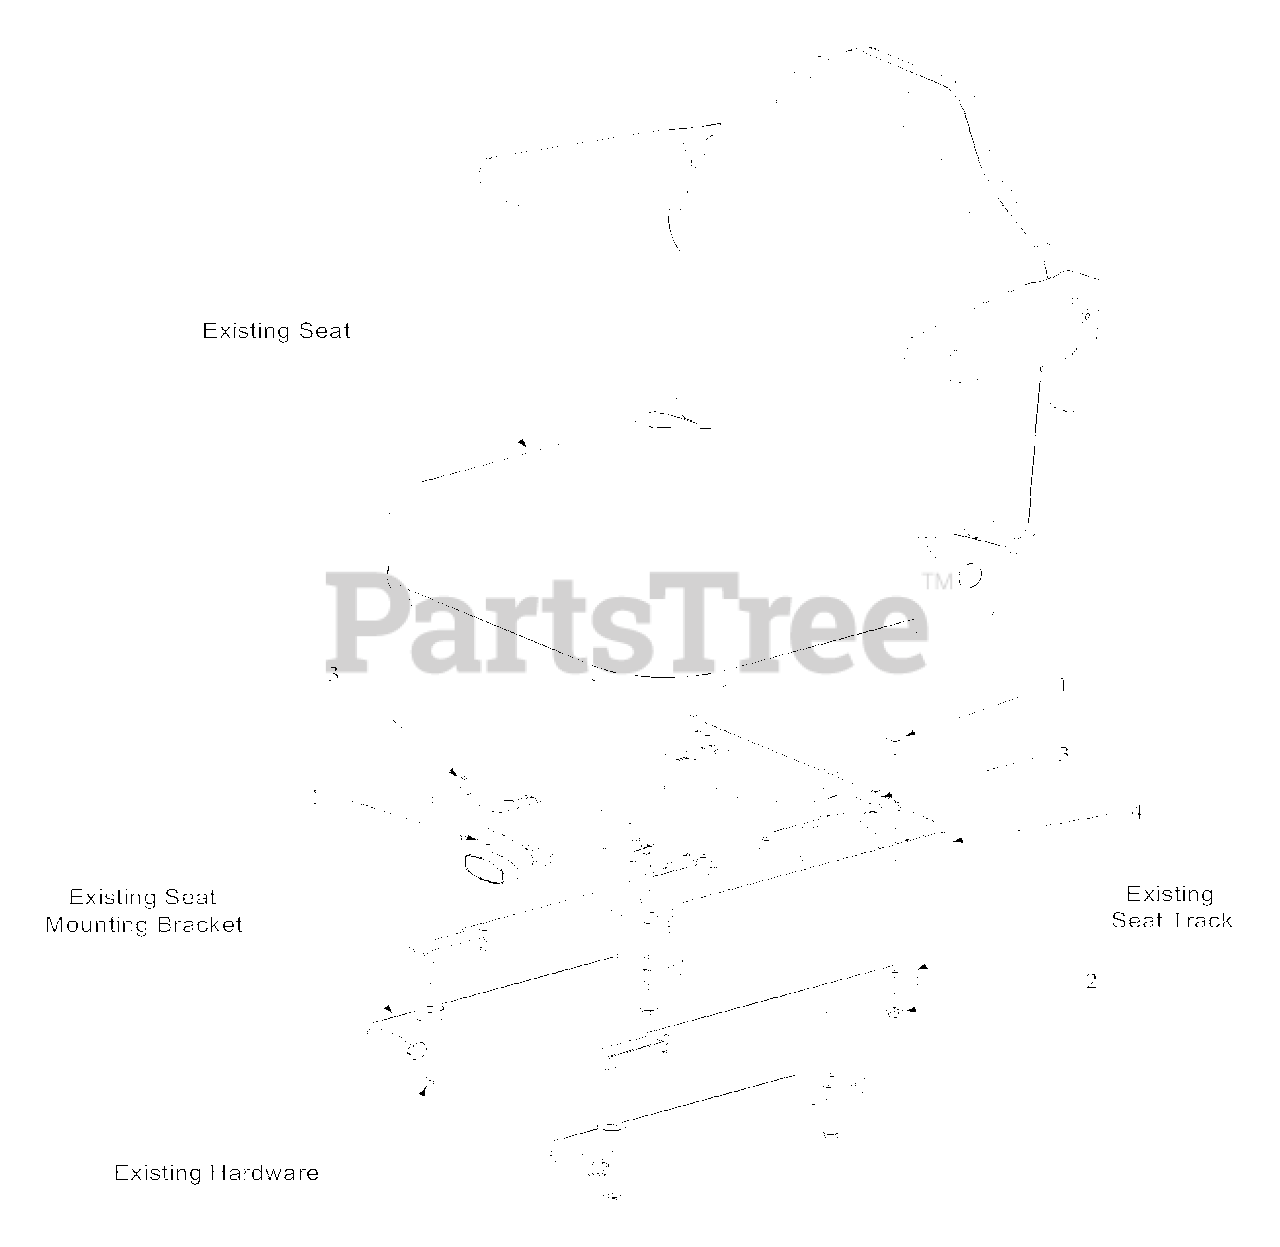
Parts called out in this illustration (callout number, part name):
1	Carriage Bolt, 5/16-18 x .75
2	Nut, Hex Flange Lock, 5/16-18
3	HHCS, 5/16-18 x .75
4	Seat Suspension
